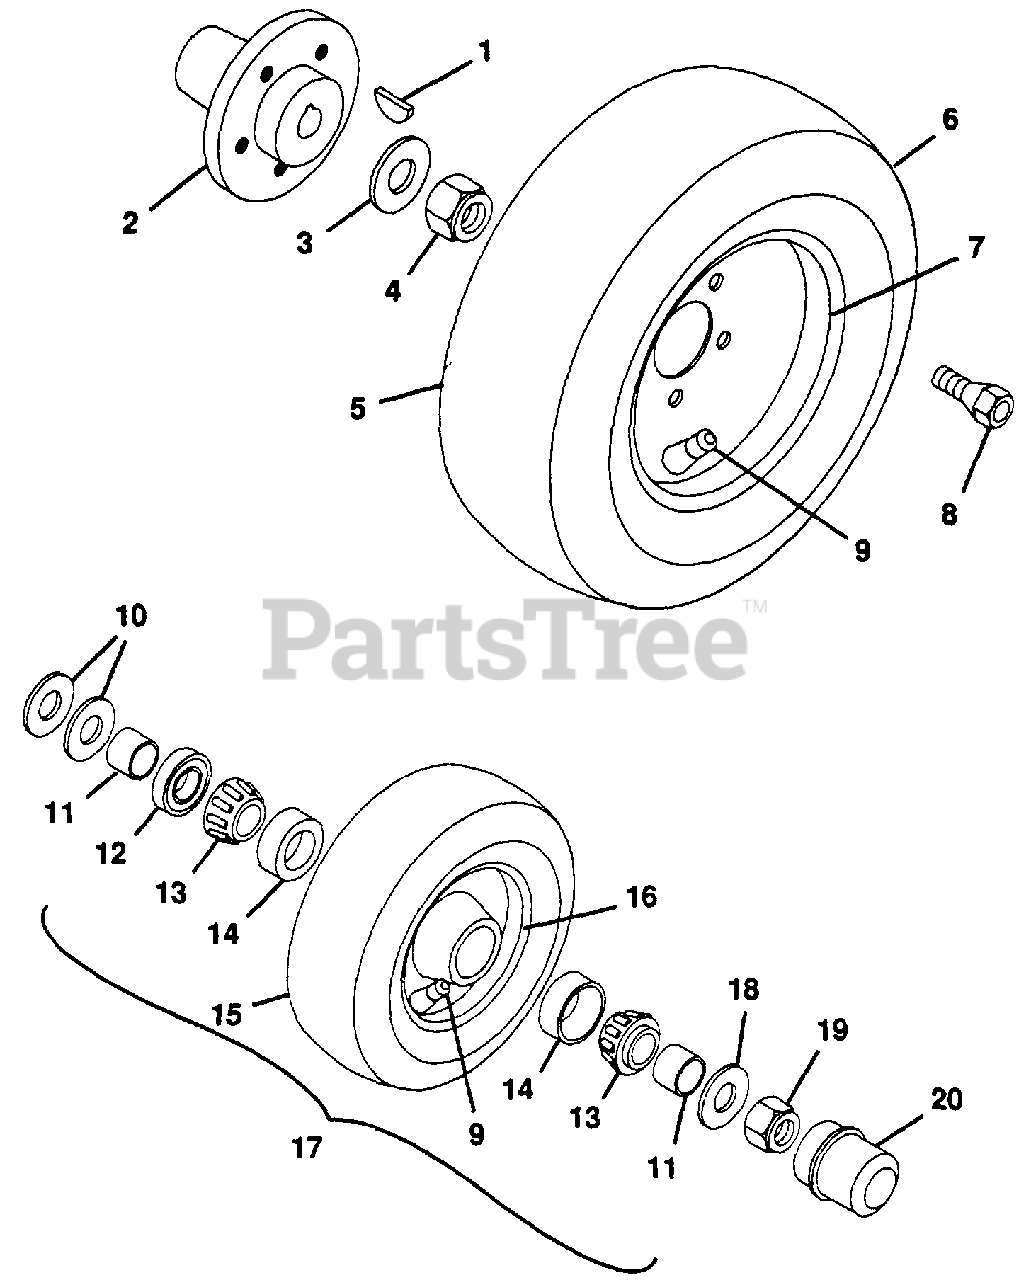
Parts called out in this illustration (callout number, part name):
1	KEY, WOODRUFF .250X2.125 SOFT
2	HUB, TAPERED 4-WHEEL
3	WASHER, FLAT .813X2.0X.148
4	NUT, LOCK 3/4-10
5	ASM, REAR WHEEL 23X8.50-12
5	ASM, WHEEL R.H. 23X8.5-12 SGT
5	ASM, WHEEL L.H. 23X8.5-12 SGT
5	ASM, REAR WHEEL 23X10.50-12
6	TIRE, REAR 23X8.50-12
6	TIRE, SUPER TERRA 23X8.50-12
6	TIRE, REAR 23X10.50-12
7	RIM, WELDMENT
8	BOLT, HUB 7/16-20X.75(SPECIAL)
9	ASSEMBLY, VALVE STEM
10	WASHER, FLAT .813X1.37X.100
11	SPACER
12	SEAL, OIL
13	BEARING, CONE LM 11949
14	BEARING, CUP LM 11910
15	TIRE, FRONT 16X6.50-8
15	TIRE, FRONT 16X7.50-8
16	RIM, FRONT WHEEL ASSEMBLY
17	ASSEMBLY, FRONT WHEEL 16X6.50-8
17	ASSEMBLY, FRONT WHEEL 16X7.50-8
18	WASHER, FLAT .656X1.312X.095
19	NUT, LOCK 5/8-11
20	CAP
